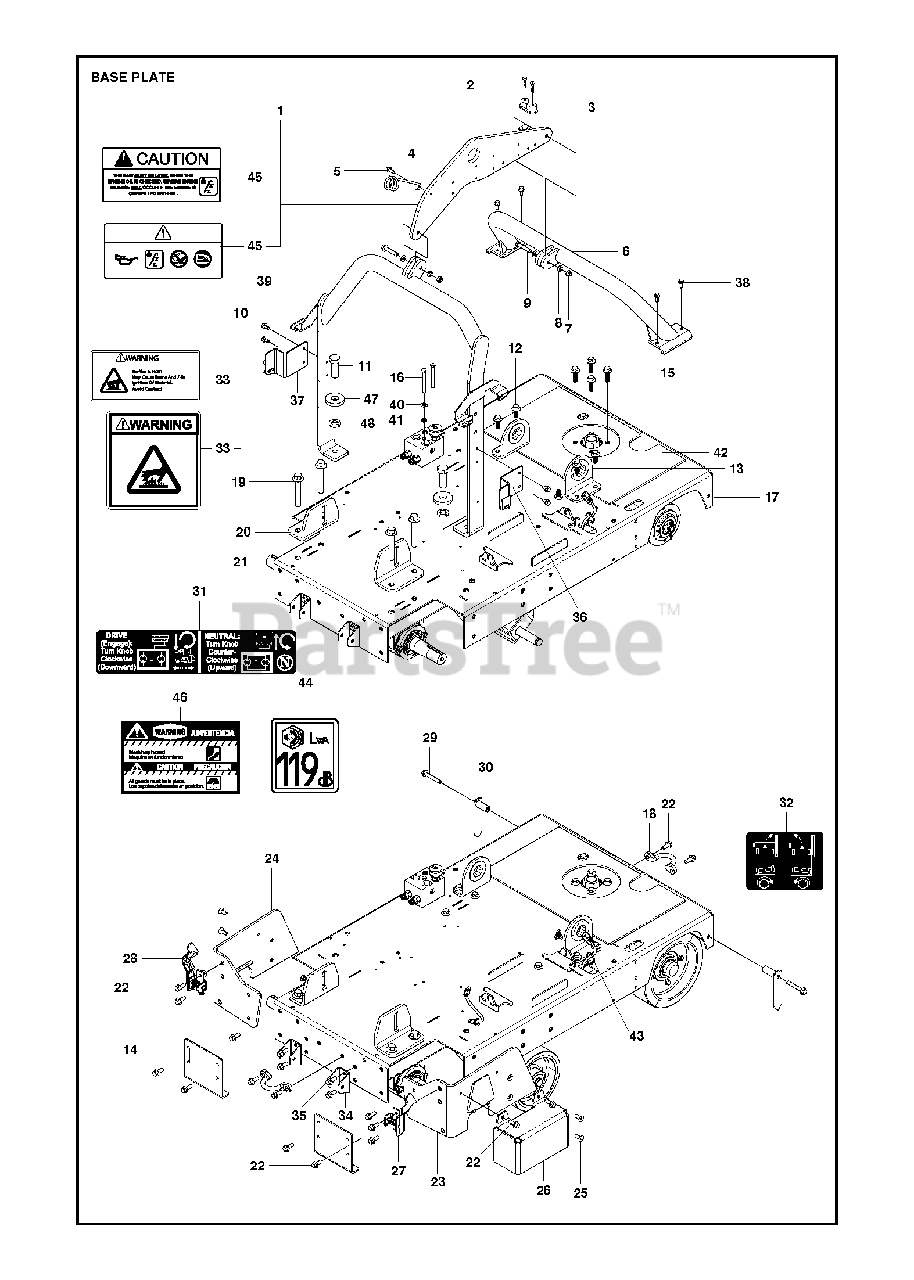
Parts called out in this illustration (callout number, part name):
7	HEXAGON LOCKING NUT
8	WASHER
40	SPRING WASHER
41	WASHER
